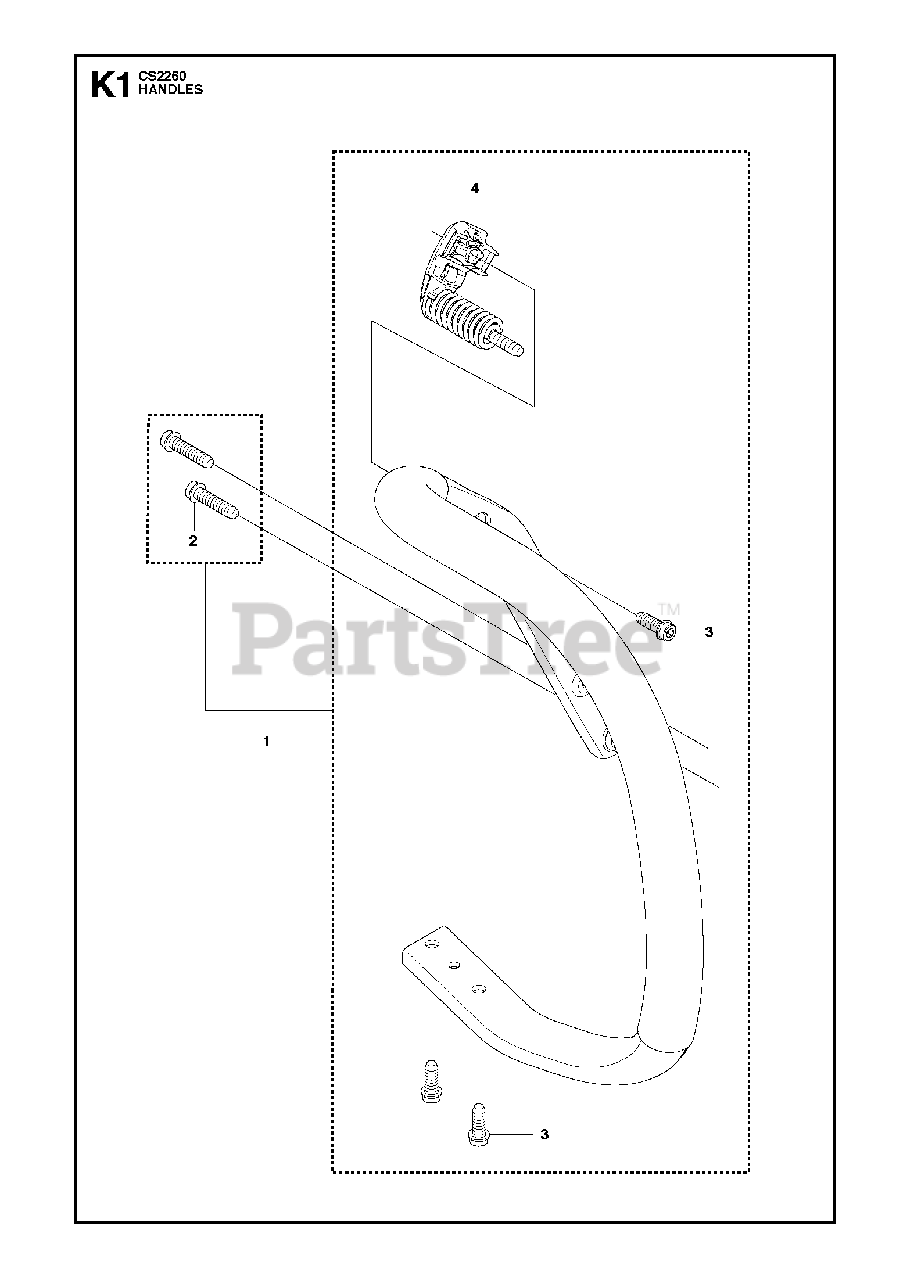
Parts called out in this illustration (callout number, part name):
1	FRONT HANDLE
2	SCREW
3	SCREW IHSCFT
4	ANTIVIBRATION ELEMENT
